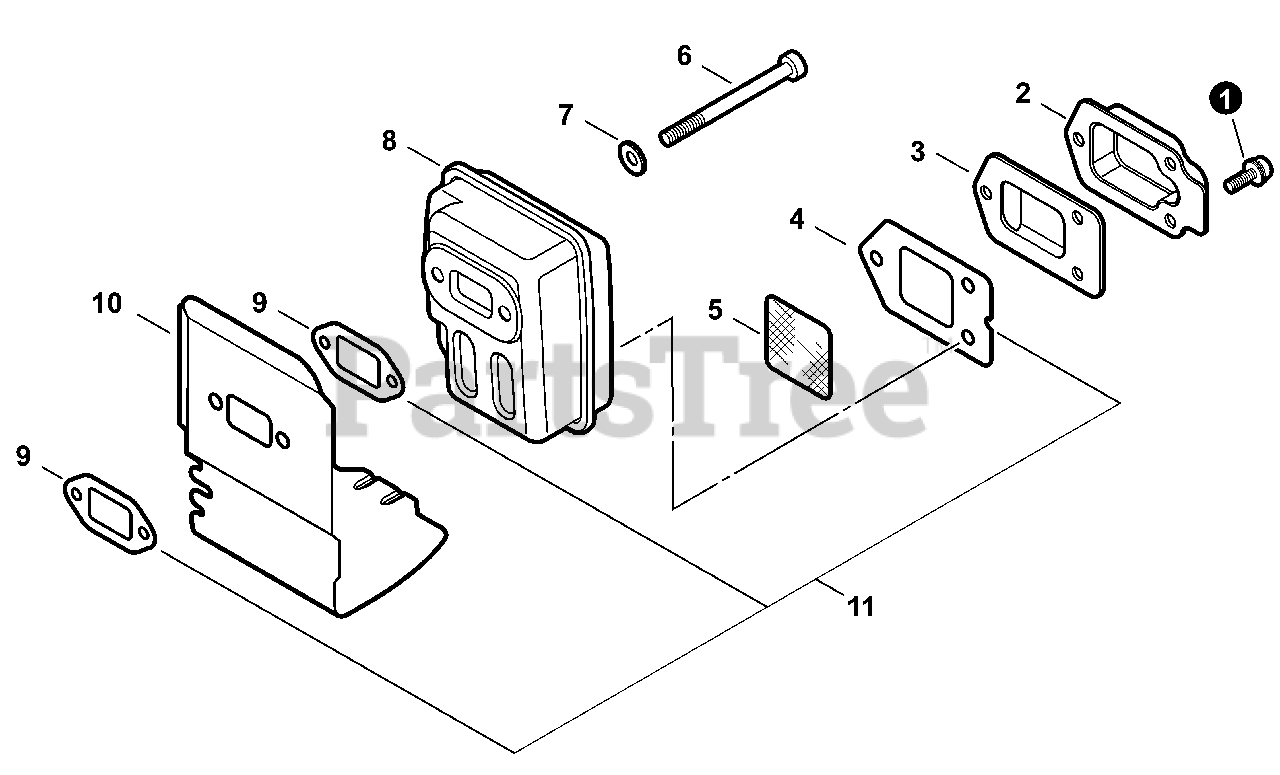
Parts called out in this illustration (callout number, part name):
1	SCREW 4×10
2	GUIDE, EXHAUST - INNER
3	GUIDE, EXHAUST
4	GASKET, EXHAUST
5	SCREEN, SPARK ARRESTER
6	BOLT 5×55
7	WASHER, FLAT 5.5×10×0.8
9	GASKET, EXHAUST
10	HEAT SHIELD, EXHAUST
11	GASKET KIT
